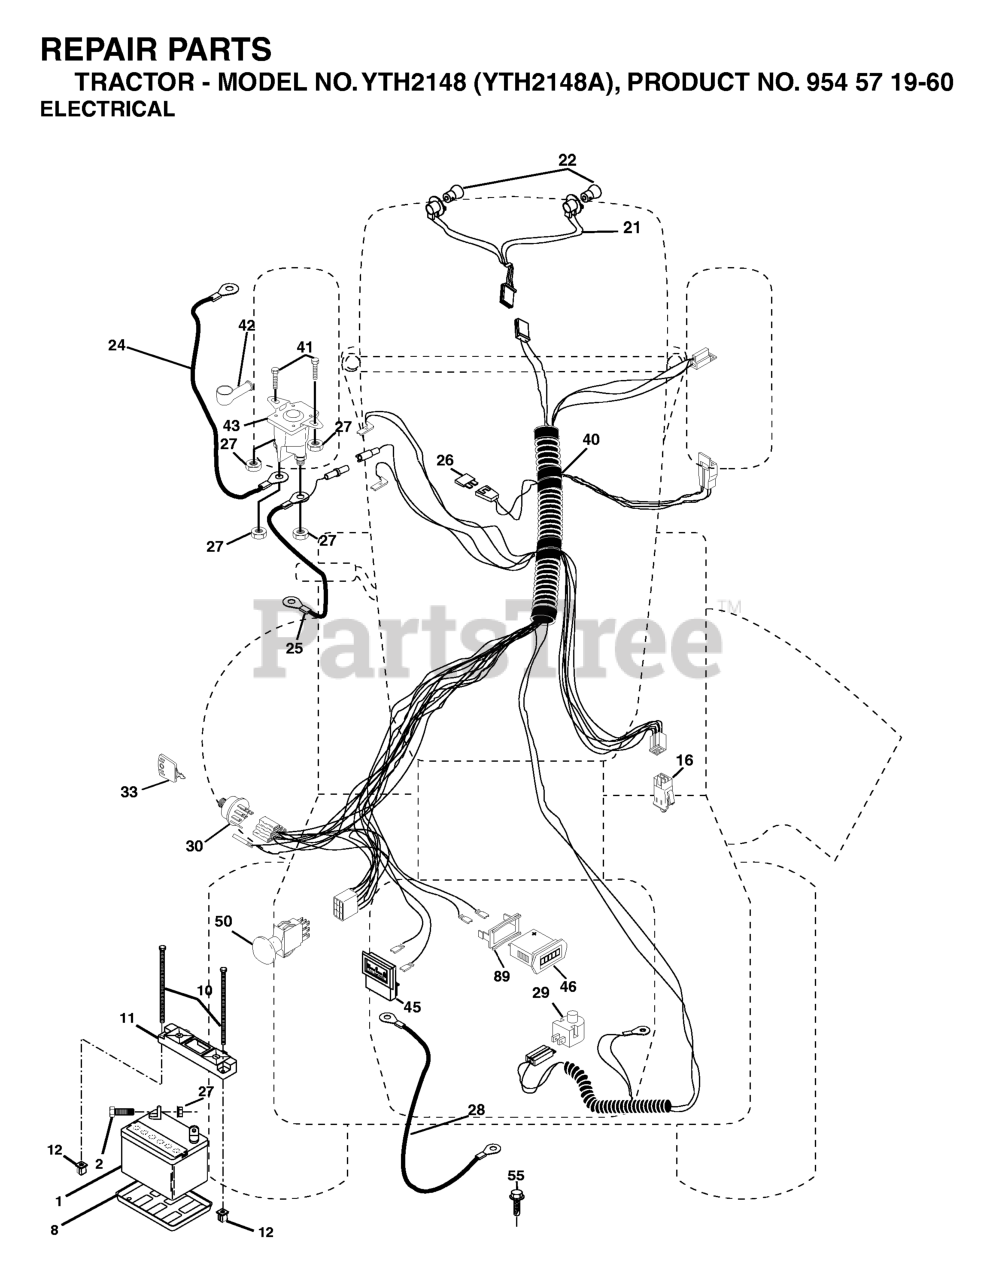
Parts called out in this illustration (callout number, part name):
1	BATTERY 12V .35 AMP
2	BOLT.HEX.1/4.X.3/4.DICHROMATE
8	BATTERY TRAY T
10	BOLT 1/4-20 X 7.5
11	BATTERY HOLDDOWN FRONT MOUNT
12	NUT, PUSH NYLON 1/4" BATTERY
16	SWITCH INTERLOOK PUSH-IN
21	HARNESS ASSY LIGHT
24	BATTERY CABLE GT
25	CABLE BATTERY 6 GA 22" W/16W
26	FUSE 20AMP
27	NUT
28	CABLE GROUND 6 GA 21" 90T BLK
29	RP.SWITCH.PLUNGER.NC.GRAY
30	IGNITION SWITCH
33	KEY MLD GEN DELTA
40	HARNESS.IGNITION
41	BOLT
42	TERMINAL COVER
43	SOLENOID
46	HOUR METER
50	RP.PTO.SWITCH.8 TERMINAL.BLACK
55	Screw 5/16-18 x 1/2 Hex, Self Tapping 5/16-18 x 1/2
89	BRACKET SNAP-IN HOURMETER
